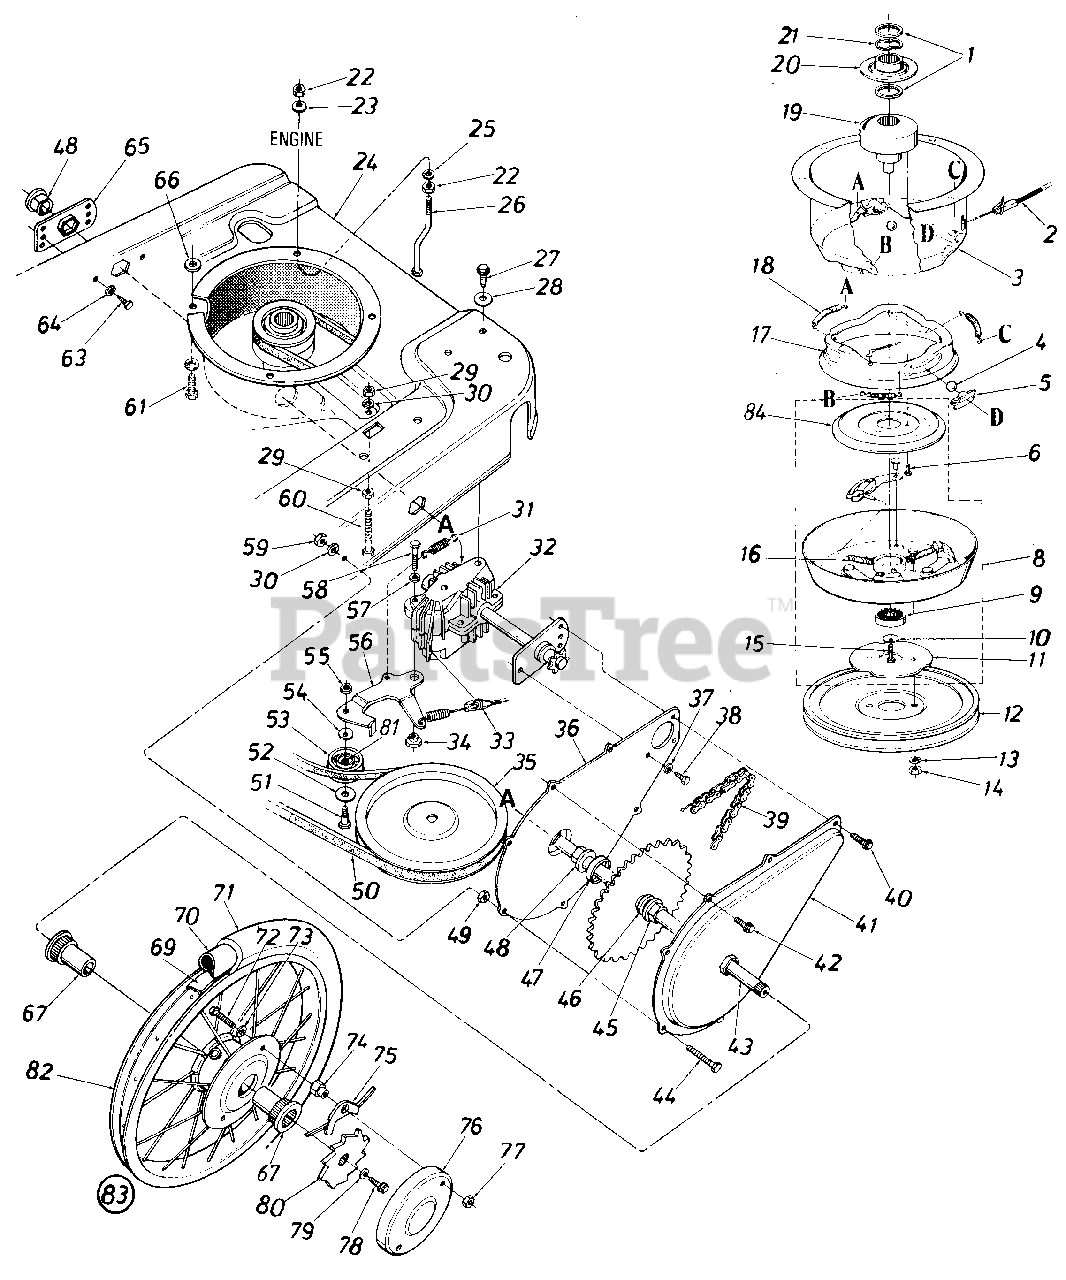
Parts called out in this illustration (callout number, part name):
1	Washer 1.0" I.D. x 1.2" O.D.
2	BBC Clutch Cable 46" Lg.
3	Clutch Housing
4	Steel Ball .500" Dia.
5	Ball Block
6	Hex Wash. TT-Tap Cl. Scr. 1/4-20 X .50" Lg.
8	Clutch Blade Housing Ass'y.
9	Ball Brg. .669" I.D. x 1.574" 0. D.
10	Bell-Wash 44" I.D. x .87" 0. D.
11	Blade Disc.
12	5/8 "V"-Pulley 1.58" I.D. x 8.0" O.D.
13	L-Wash. 3/8" I.D.
14	Hex Nut 3/8-24 Thd.
15	Hex Bolt 7/16-20 x 2.0" Lg. Gr. 5
16	Comp. Spring .33" O.D. x 2.05" Lg.
17	Brake Cup Cone
18	Extension Spring .35" O.D. x 1.80" Lg.
19	Fixed Pulley MBC Adapter
20	Movable Pulley Half
21	Wave Wash. .164 High x 1.005" I.D.
22	Hex Nut 5/16-18 Thd.
23	Bell-Wash. .336" I.D. x .860" O.D.
24	Hi-Wheel Frame
25	L-Wash. 5/16" I.D.
26	Belt Guard 5/16" Bolt
27	Hex Wash. Hd. B-Tap Scr. 5/16-18 x .50" Lg.
28	Bell-Wash. .400" I.D. x 1.13" O.D.
29	Hex Nut 1/4-20 Thd.
30	L-Wash. 1/4" I.D.
31	Extension Spring .33" I.D. x 1.12" Lg.
32	Transmission Comp.
33	Self-Propelled Cable x 50" Lg . Black
34	Shld. Spacer .375" Dia. x . 170
35	Fl-Pulley 5.06" O.D.
36	45 Tooth Chain Cover
37	L-Wash. 1/4" I.D.
38	Hex B-Tap Scr. 1/4 X .38" Lg.
39	#48 Chain .500" Pitch x 52 Links
40	Hex Wash. TT-Tap Scr. 1/4-20 X .50" Lg.
41	45 Tooth Chain Case
42	Hex B-Tap Scr. 1/4 X .38" Lg.
43	Rear Axle Ass'y. 26.82" Lg.
44	Hex Bolt 1/4-28 X .88" Lg.
45	Hex Flange Brg. .631" I.D. x .320
46	Fl-Wash. .635" I.D. x 1.0" O.D.
47	Spacer .630" I.D. x 1.250" O.D.
48	Hex Flange Brg. .631" I.D. x .720
49	Hex Jam Nut 1/4-28 Thd.
50	"V"-Belt
51	Shld. Bolt .375" Dia. x .400 Lg.
52	Fl-Wash. .390" I.D. x 1.00" O.D.
53	Fl-Idler Plastic 1.50" Dia. x .48
54	Bell-Wash. .265" I.D. x .75" O.D.
55	Hex Nut 1/4-28 Thd.
56	Idler Brk't. Ass'y.
57	L-Wash. 1/4" I.D.
58	Hex Bolt 1/4-20 X 1.25" Lg.
59	Hex Nut 1/4-28 Thd.
60	Hex Bolt 1/4-20 X 2.00" Lg.
61	Hex Wash. Hd. TT-Tap Scr. 3/8-16 x 1.0" Lg.
63	Hex B-Tap Scr. 1/4 X .38" Lg.
64	L-Wash. 1/4" I.D.
65	Hex Bearing Cup
66	Fl-Wash. .406" I.D. x .7341' O.D.
67	Flange Bearing .630" I.D. x 2.83" Lg.
69	Rimstrip 16 x 7/8
70	Inner Tube 16 x 2.12
71	Chevron Tire 16 x 2.125
72	Hex Bolt Special 5/16-18 x 1.0" Lg.
73	Intern. L-Wash. 5/16" I.D.
74	Special Hex Nut 5/16-18 Thd.
75	Pawl and Spring Ass'y.
76	Wheel Cover 4.75" I.D.
77	Hex Nut 5/16-18 Thd.
78	Hex Wash. Hd. Self-Tap Screw 1/4" X 3/4" Lg.
79	Bell-Wash. .265" I.D. x .75" O.D.
80	Wheel Ratchet 2.92" O.D.
81	Needle Brg. .375" x .31
82	Rim Ass'y. Only 16.0" x 2.1
83	Wheel Ass'y. Comp. 16 x 2.12
84	Clutching Cone
